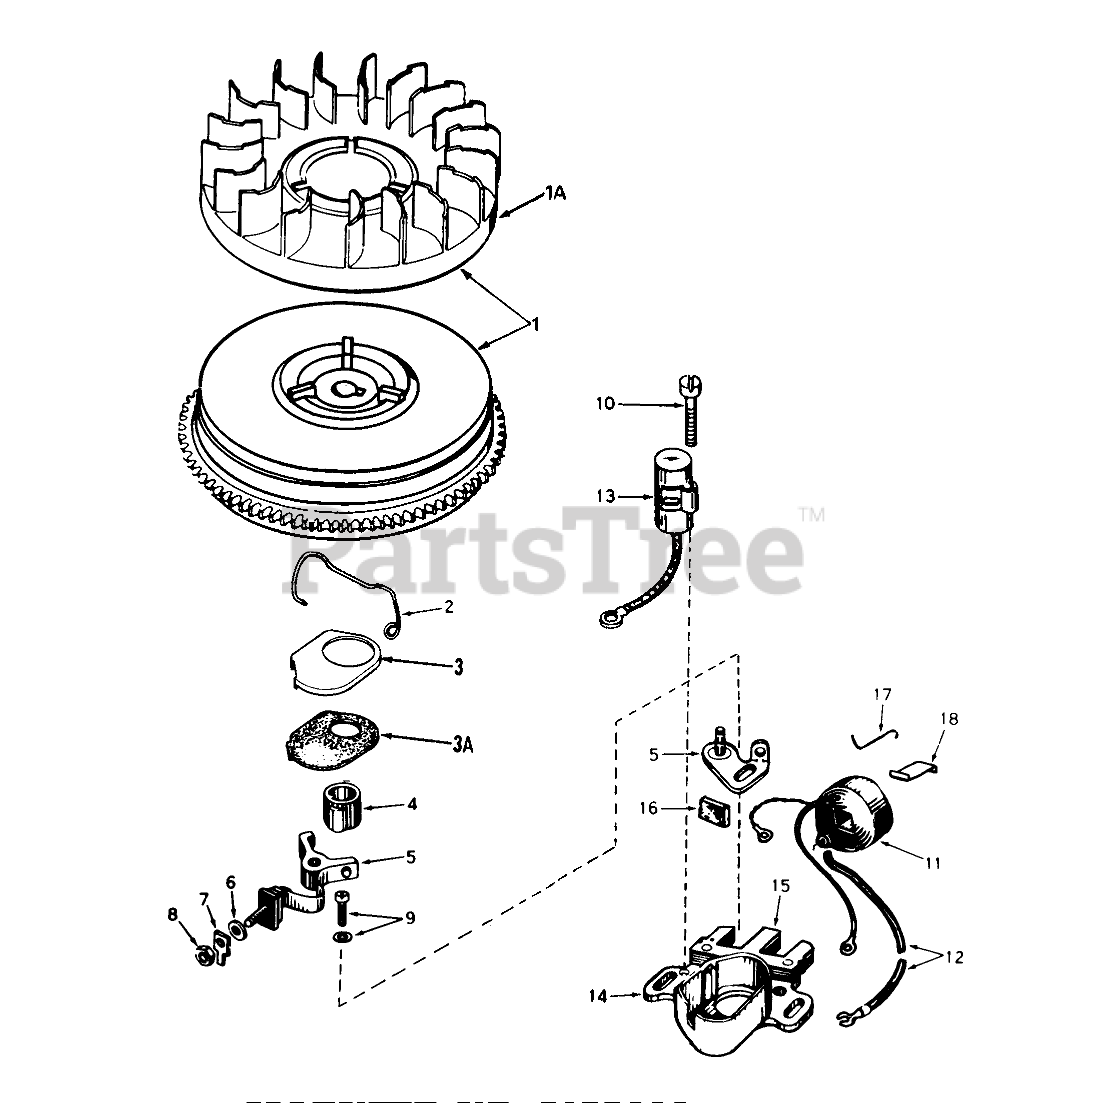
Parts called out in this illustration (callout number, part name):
1	Flywheel (Incl. #1A, 3 & 3A)
2	Spring Breaker Box
3	Cover-Dust
3A	Gasket, Dust Cover
4	Cam-Breaker
5	Breaker Assy.
7	Terminal, Ground
9	Breaker Screw
10	Condenser Screw
11	Coil Assy. (Incl. #12)
12	Wire, Lead
13	Condenser
14	Core & Plate
15	Stator Assy. (Incl. #2, 3, 3A, 5 thru 14 & 16 thru 18)
16	Felt,Cam Wiper
17	Clip, Coil
18	Spring Coil Wedge
